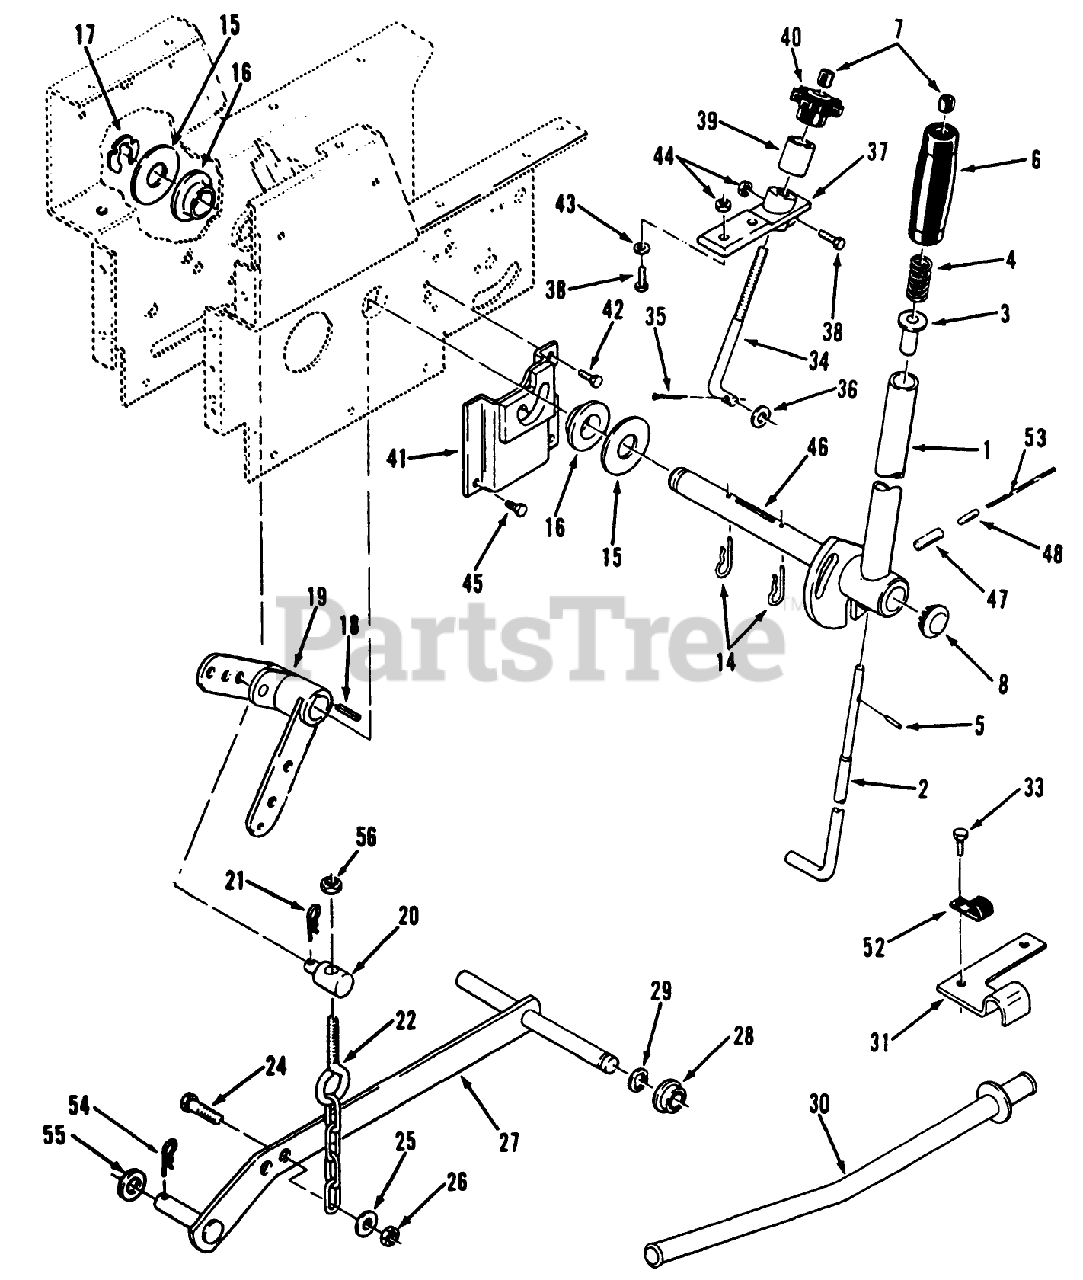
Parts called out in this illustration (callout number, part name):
2	ROD-LATCH LIFT
3	RETAINER-SPRING
4	SPRING-COMPRESSION
5	PIN-SPIROL
6	HANDGRIP
7	CAP-ROD, PLUNGER
8	PLUG
14	Pin-Cotter
15	WASHER-FLAT
16	BEARING-FLANGE
18	KEY-SQUARE
19	LIFT LEVER ASM
20	TRUNNION-LIFT
21	Hairpin
22	CHAIN-LIFT
24	SCREW-HH
25	WASHER-PLAIN
26	NUT-LOCK, NI
28	BUSHING
33	SCREW-HH, LOCK
34	ROD-HEIGHT CONTROL
35	PIN-COTTER
36	WASHER-FLAT
38	SCREW-HH
40	KNOB-LIFT CONTROL
42	SCREW
43	WASHER-PLAIN
44	NUT-LOCK, NI
46	SHAFT-LIFT LEVER
47	PIN-SPRING
48	PIN-ROLL
52	CLIP
53	Lock Wire
54	Hairpin Cotter
55	WASHER-FLAT
56	NUT-LOCK, NI
